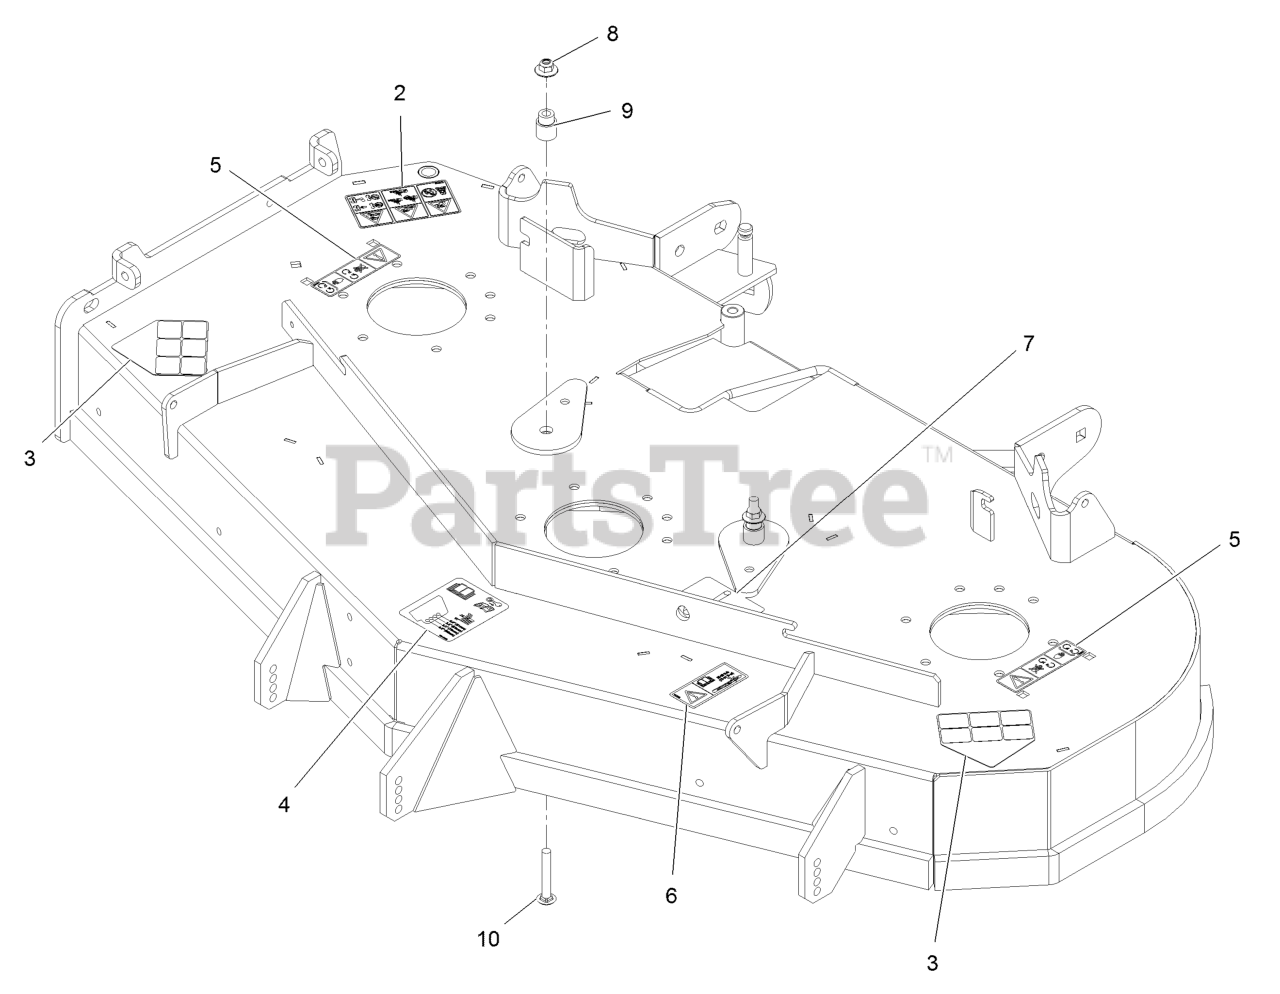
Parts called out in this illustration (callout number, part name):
2	DECAL-DANGER
3	DECAL-DANGER
4	DECAL-ROLLER, ANTI-SCALP
5	DECAL-COVER, MISSING
6	DECAL-BOLT TORQUE
7	DECAL-BELT ROUTING
8	Nut-Nyloc 3/8-16 Flg
9	BUSHING-IDLER
10	SCREW-CARR
